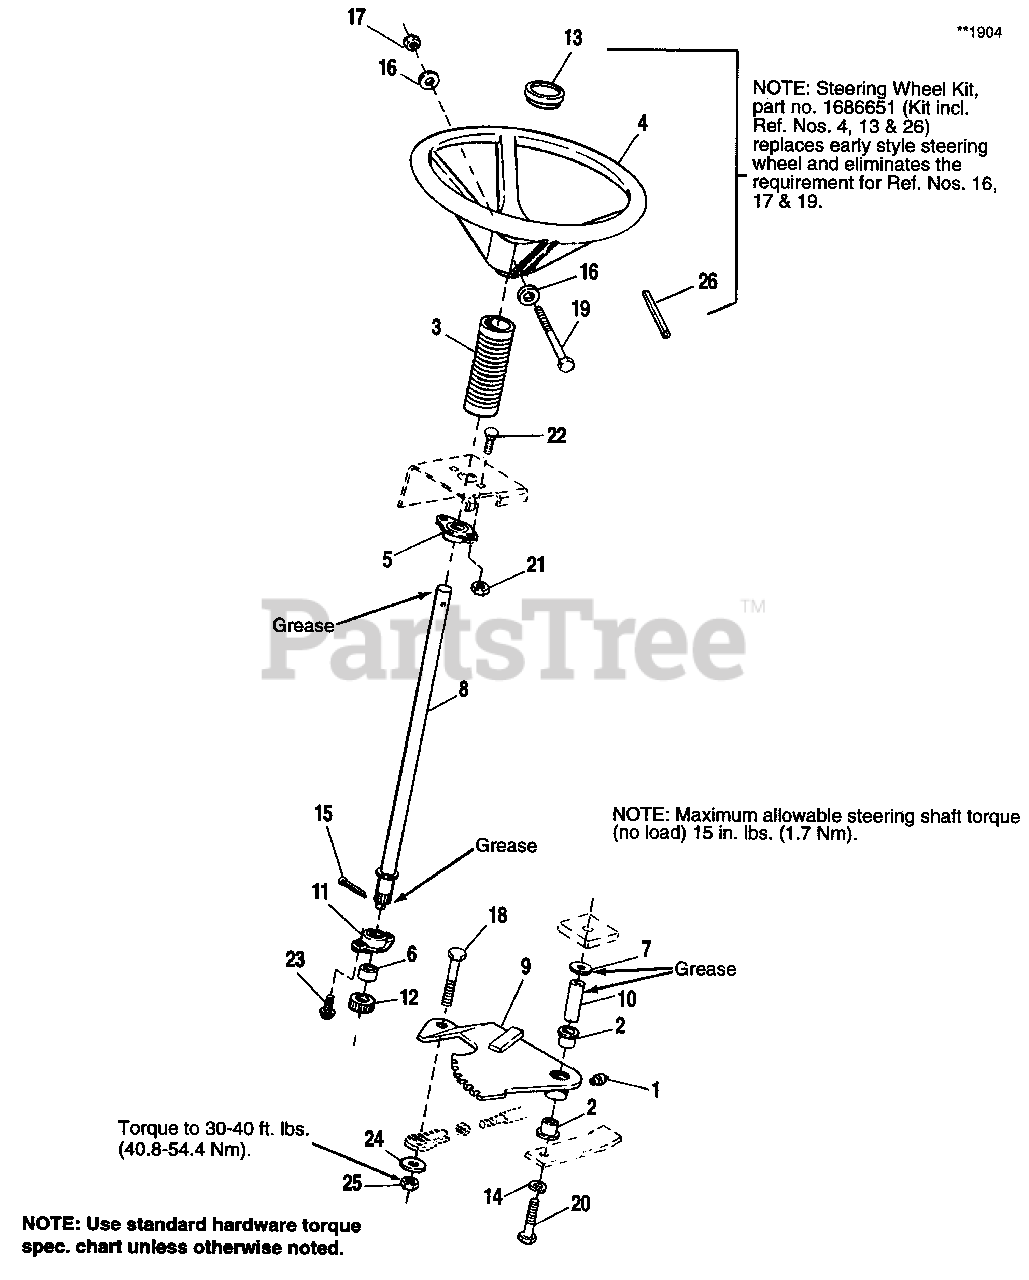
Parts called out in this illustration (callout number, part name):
1	FITTING, Lube
3	TUBE, Steering Shaft
4	STEERING WHEEL KIT (Incl. Ref. Nos. 13 & 26)
5	BEARING, Flange
6	SPACER, Steering Shaft
7	WASHER, Nylon
8	SHAFT ASSY., Steering
9	ARM ASSY.
11	BEARING, Flange
12	PINION, Steering Shaft
13	CAP, Steering Wheel
14	LOCKWASHER, 1/2
15	PIN, Cotter
16	WASHER, 5/16
17	NUT, Hex, ESNA Lock, 5/16-18
18	CAPSCREW, Hex,1/2-13 x 1-1/2
19	CAPSCREW, Hex, 5/16-18 x 3-1/2
20	CAPSCREW, Hex, 1/2-13 x 2-1/4
21	NUT, Hex, Whizlock, 5/16-18
22	CARRIAGE BOLT, 5/16-18 x 3/4
23	SCREW, Whizlock, 3/8-16 x 3/4
24	WASHER, 1/2 x 1
25	NUT, Hex, ESNA, 1/2-13 (Thin)
26	PIN, Spring, 5/8 x 2
